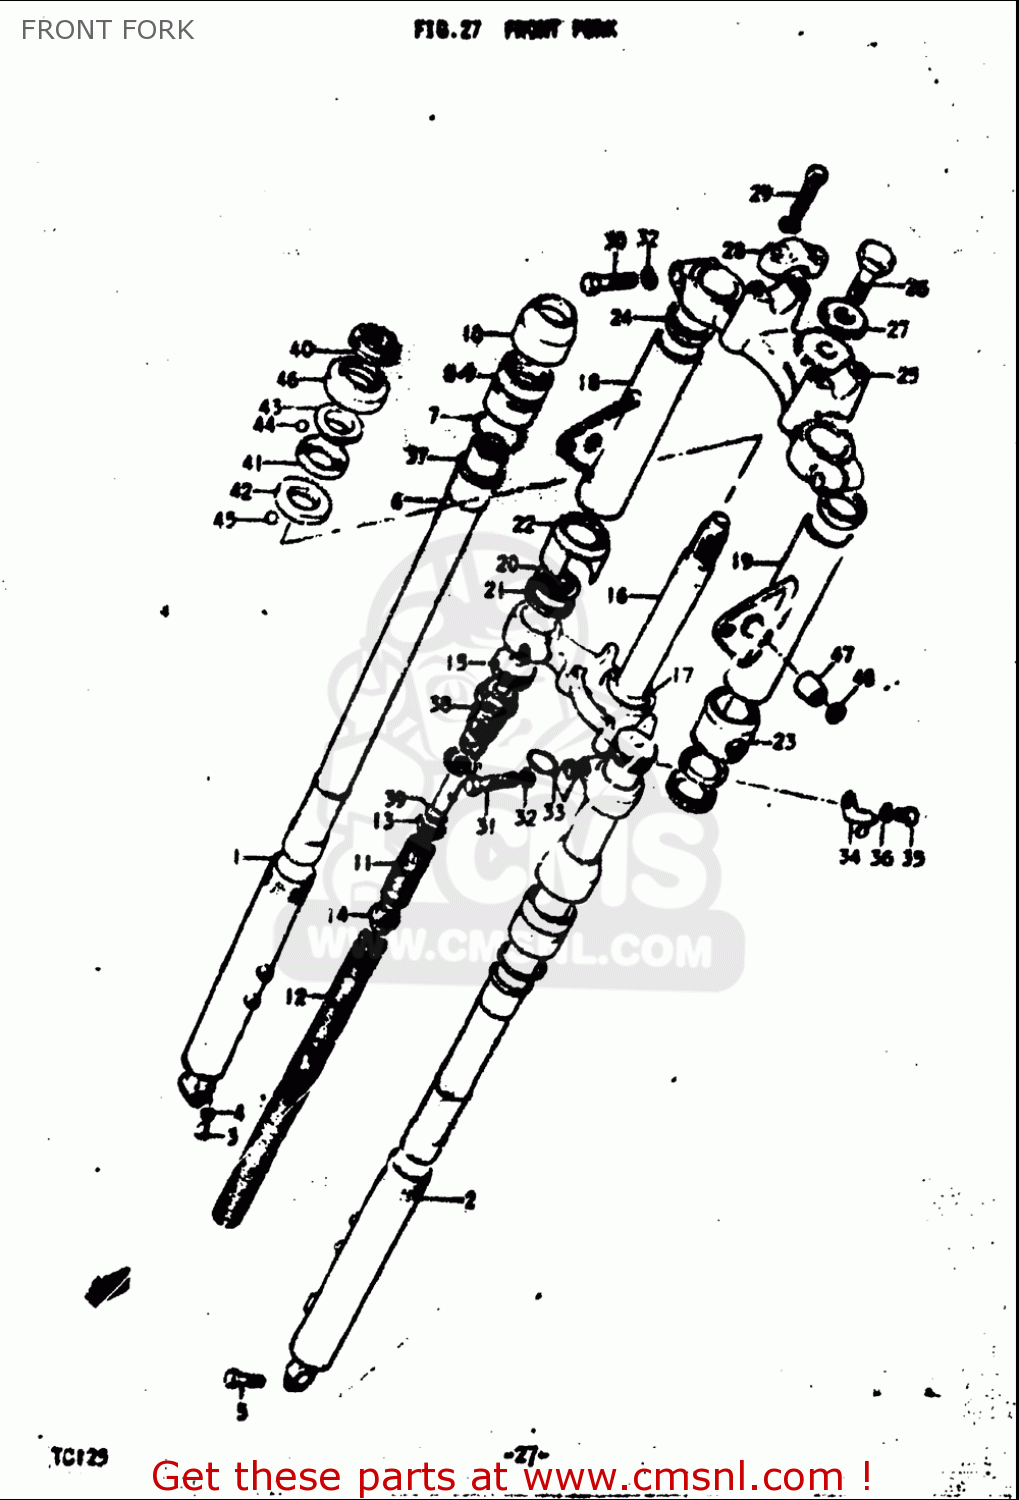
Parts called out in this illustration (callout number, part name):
3	SCREW
4	GASKET,DRAIN,PLUG (NAS)
5	BOLT
7	O RING,OIL SEAL LWR
9	SEAL,OIL
10	SEAL,DUST
13	GUIDE,SPRING
17	RACE,STEERING OUTER LWR
18	BRACKET,HEADLAMP HOUSING
19	BRACKET,HEADLAMP,LEFT
21	GUIDE, COVER
22	CUSHION,HEADLAMP BRACKET
24	SEAT,HEADLAMP BRACKET
26	BOLT,FR FORK(10X33)
27	WASHER
29	BOLT
32	WASHER,LOCK
34	CLIP
35	SCREW
36	WASHER,LOCK
38	CAP
39	SEAT,SPRING
40	NUT,STEERING STEM(25X44X10)
41	RACE,STEERING INNER UPR
42	LACE,STEERING INNER LWR
43	RACE,STEERING OUTER UPR
44	BALL
45	BALL
46	STEERING DUST S
47	COVER,FRONT TURN SIGNAL BRACKET
48	WASHER
